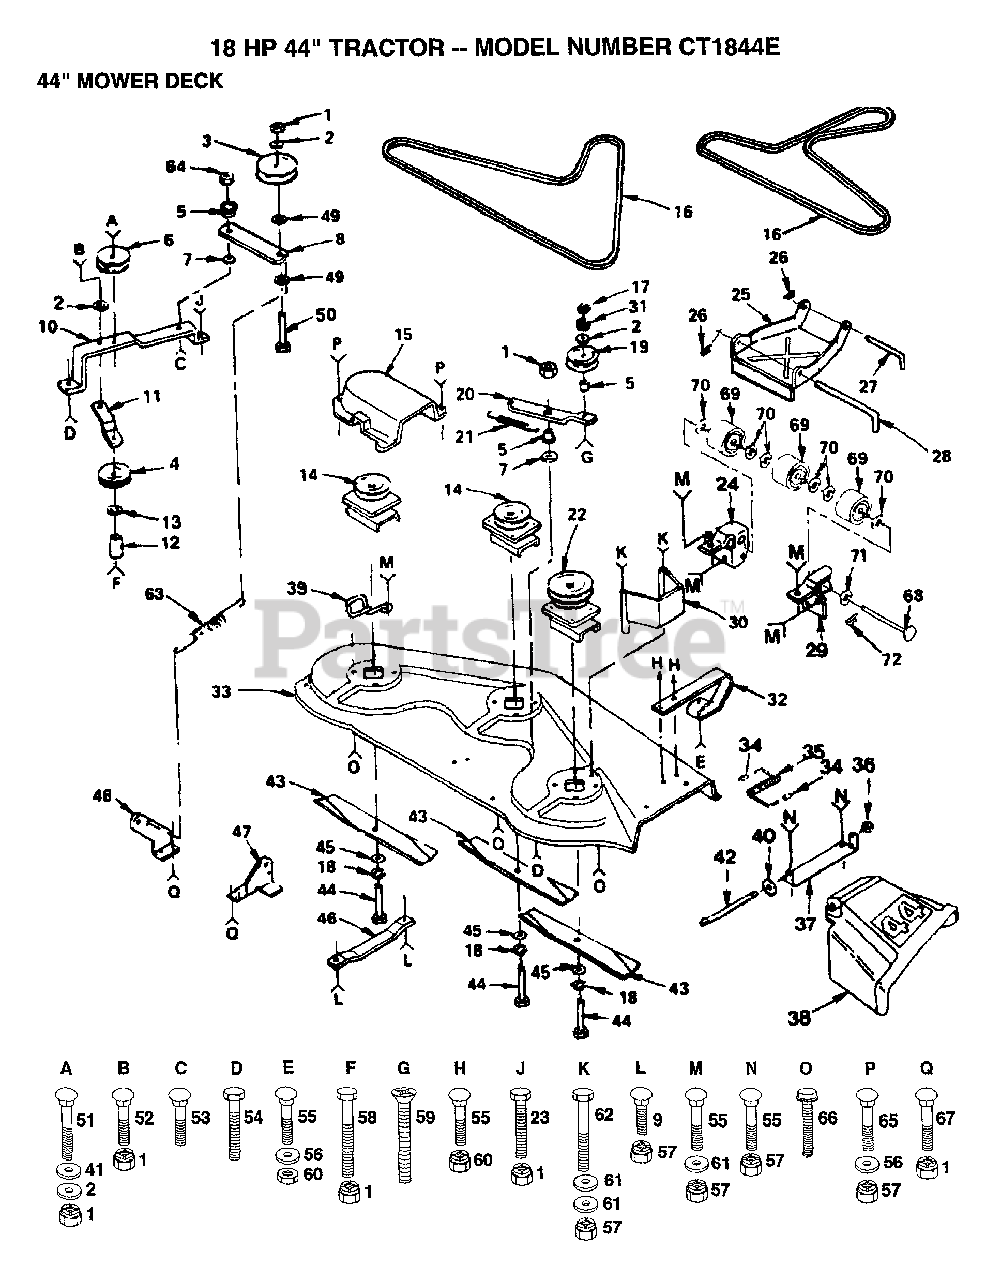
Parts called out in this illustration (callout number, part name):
2	WASHER
3	PULLEY IDLER
4	IDLER-FLAT T
5	SPACER RETAINER
6	IDLER-INSIDE T
7	"WASHER, WEAR LT"
8	ARM IDLER
9	BOLT
10	"SUPPORT YT, BAR"
11	BRACE-IDLER YT
12	SPACER
13	WASHER
15	GUARD YT
16	BELT-V.79.1.MWR
17	NUT.HEX.3/8-16UNC
19	IDLER.FLAT.GTV
20	ARM-IDLER YT
22	MANDREL PRIMARY
23	BOLT
24	BRACKET LH YTH
25	"STOP, LINK PARAL"
26	SPRING.RETAINER
27	"ROD, FRT. PARAL T"
28	HINGE PIN T
29	BRACKET RH YTH
30	GUARD BELT HYT
31	LOCKWASHER
32	RUNNER.RH
34	CAP-SLEEVE LT
36	NUT PUSH M
38	DEFLECTOR SHIELD
39	BELT RETIANER
40	WASHER
41	WASHER
42	ROD-HINGE T
44	BOLT.3/8-24X1-1/2
45	WASHER
46	RUNNER-LH M
47	BRKT SUSP REAR RH
48	BRKT SUSP REAR LH
49	WASHER
50	BOLT
51	BOLT
53	BOLT
55	BOLT
56	WASHER
58	BOLT - HEX 3/8 - 16 X 3
59	SCREW YT
61	WASHER M
62	BOLT
63	"SPRING.EXT.8.5"""
64	LOCKNUT
66	SCREW
67	BOLT
68	PIVOT PIN T
69	ROLLER T
70	WASHER T
72	COTTER PIN
